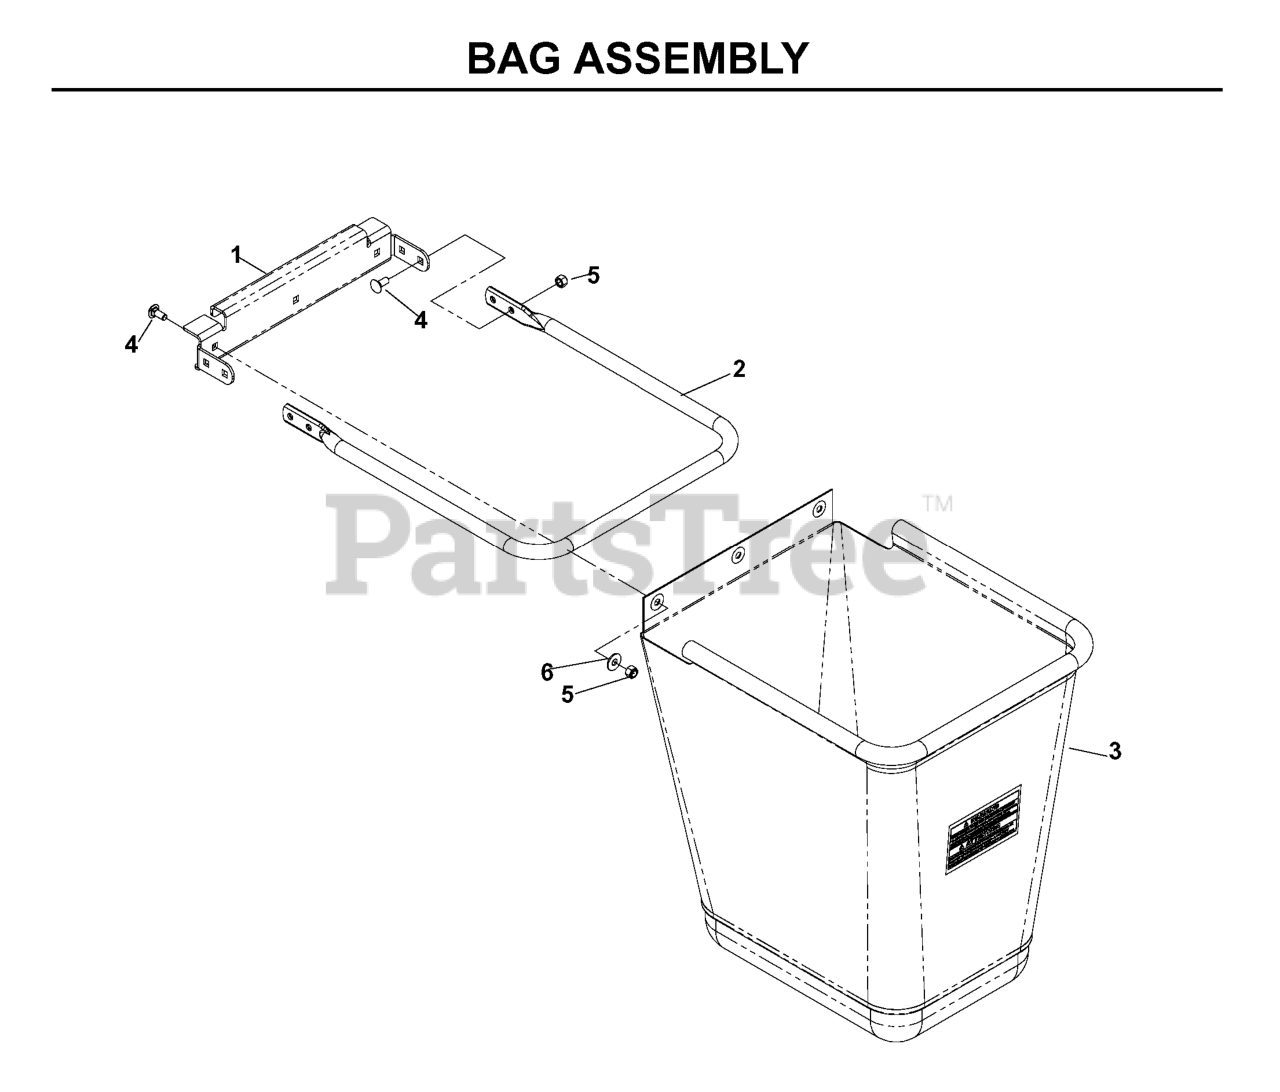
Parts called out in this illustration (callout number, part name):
1	HANGER, BAG
2	TUBE BAG FRAME
3	BAG, LARGE
4	BOLT 5/16C X 3/4" CARRIAGE
5	NUT 5/16 NYLOC
6	WASHER 5/16 FLAT
539111300	BAG, SMALL
